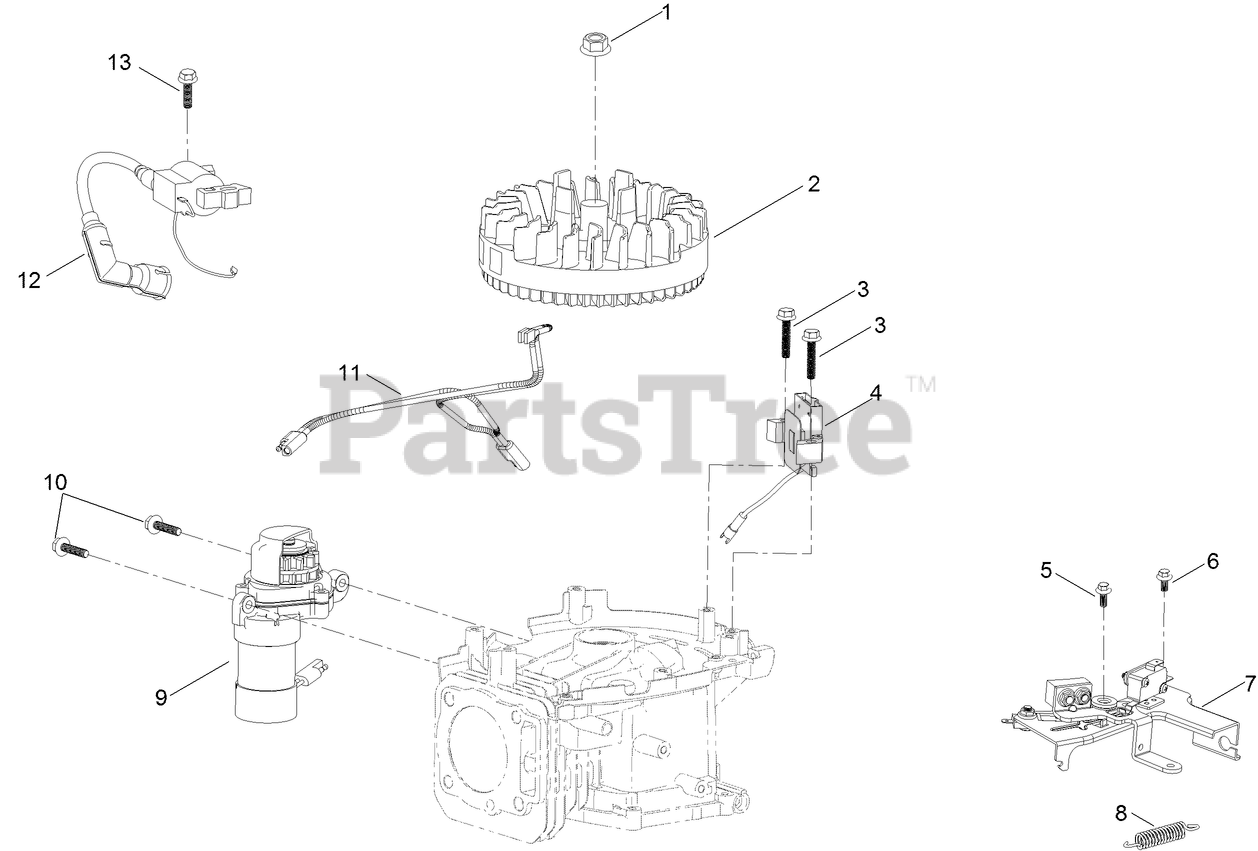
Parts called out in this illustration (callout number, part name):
1	NUT-FLANGE
2	FLYWHEEL
3	SCREW-HHF
4	ALTERNATOR
5	BOLT-FLANGE
6	SCREW-HHF
7	BRAKE ASM
8	SPRING-BRAKE
9	MOTOR-STARTER
10	SCREW-HHF
11	HARNESS-MOTOR, STARTER
12	IGNITION COIL ASM
13	SCREW-HHF
